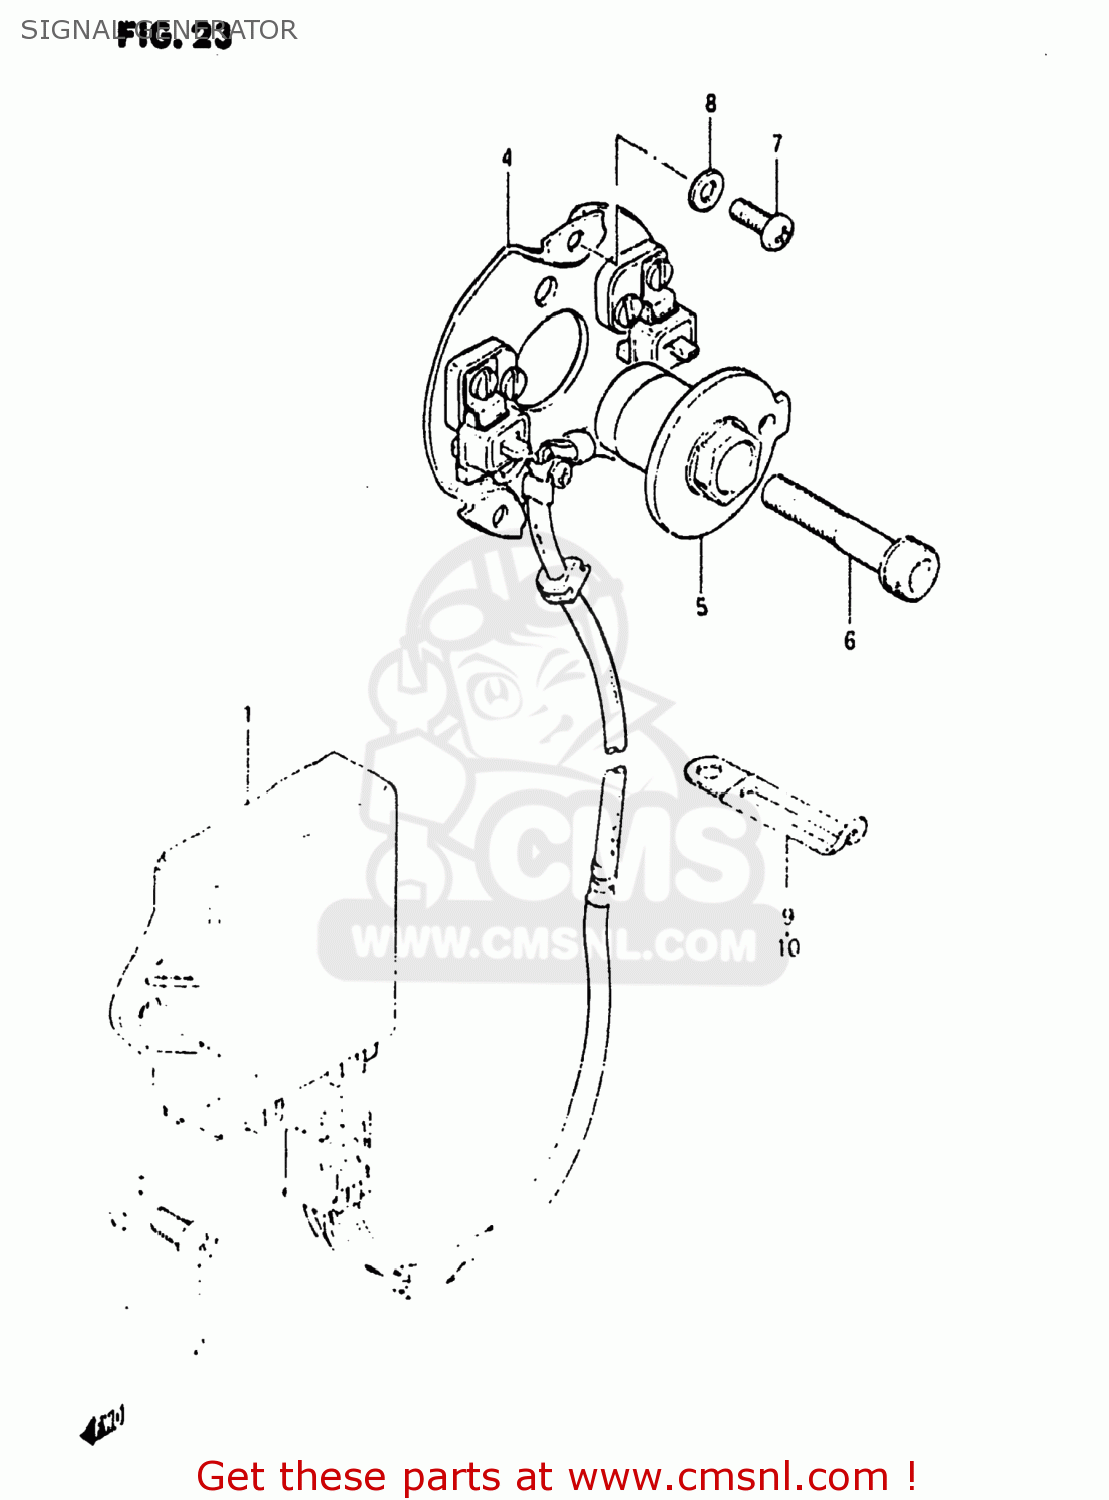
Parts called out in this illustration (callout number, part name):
1	IGNITER UNIT ASSEMBLY
2	SCREW
3	WASHER, LOWER
4	STATOR,SIGNAL GENERATOR
5	ROTOR COMP,SIGNAL
6	BOLT
7	SCREW(5X12)
8	WASHER(5.5X10X0.8)
9	CLAMP L:35
10	CLAMP
